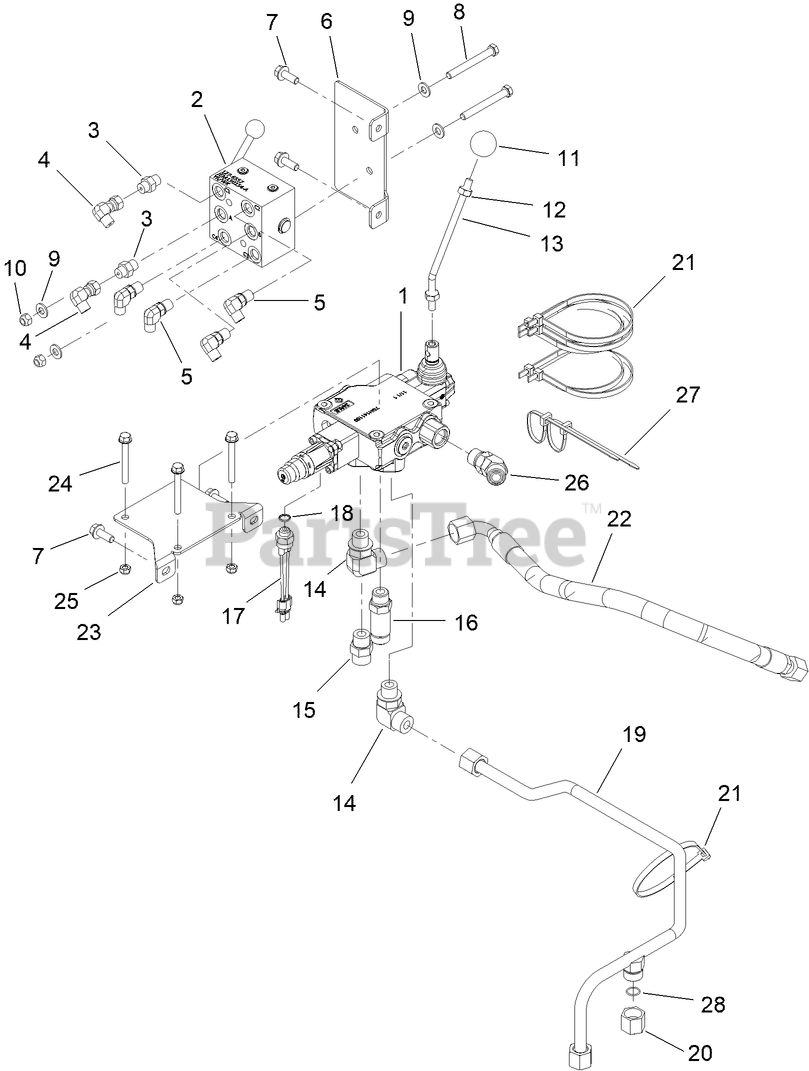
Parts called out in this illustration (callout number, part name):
1	VALVE-TRENCHER
2	CONTROL SELECTOR VALVE ASM
3	CONNECTOR (04O-06S)
4	UNION (04O-04OFX90)
5	FITTING-ELBOW, 90 DEG
6	SELECTOR VALVE BRACKET
7	SCREW-HHF
8	SCREW-HH
9	WASHER-FLAT
10	NUT-HEX
11	KNOB-ROUND
12	NUT
13	LEVER-TRENCHER
14	CONNECTOR (10S-10O90)
15	CONNECTOR (10S-10O)
16	CONNECTOR (10O-10S, LG)
17	SWITCH-BALL
18	O-RING (906 D90)
19	HARDLINE (-10 TRENCHER TO RETURN)
21	TIE-CABLE
22	HOSE (10OFX90S-26.5"-3000)
23	BRACKET-TRENCHER VALVE
24	SCREW-HHF
25	NUT-LOCK, HHF
26	CONNECTOR (10S-10O45)
27	TIE-CABLE
28	O-RING (016 D90)
